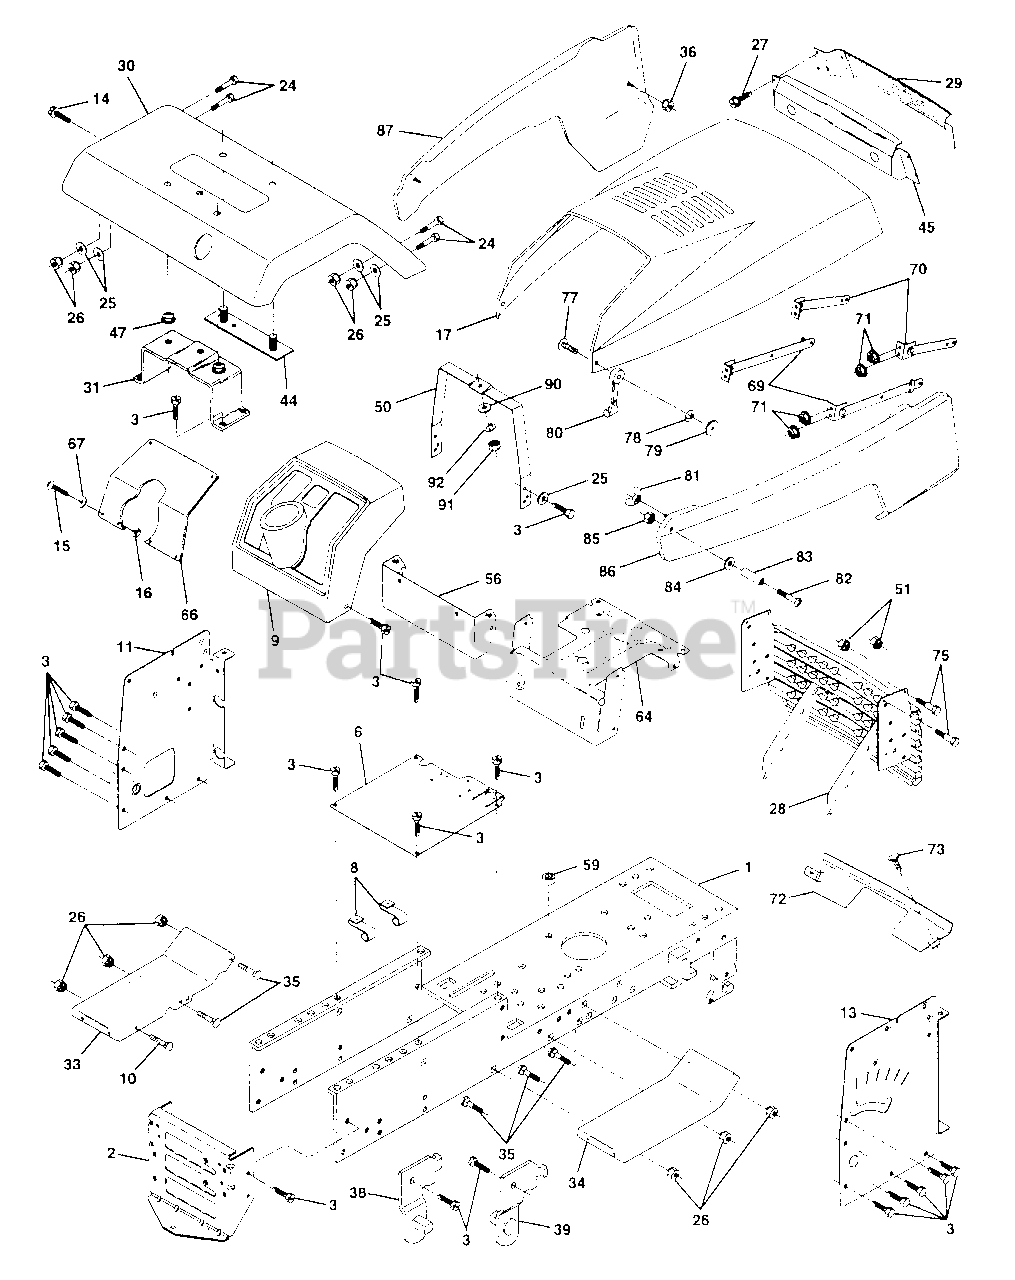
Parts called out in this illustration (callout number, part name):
1	Chassis Weldment 11 Ga
2	Drawbar Stretch
3	Screw Thdrol 3/8 - 16 x 3/4 Ty-TT
8	Clip Insulator
9	Dash Black Yard Pro
10	Bolt Carriage 3/8-16 Unc x 1
11	Panel Pnt Dash Lh
13	Panel Pnt Dash Rh
14	Screw Thdrol 3/8 - 16 x Ty-TT
15	Screw Mach Trhd 5/16 - 18 UNC x 3/4
16	Nut Keps 5/16 - 18 UNC
24	Bolt Fin Hex 3/8 - 16 Unc x 1
25	Washer 13/32 x 13/16 x 12 Ga
26	Nut Lock 3/8 - 16 Unc
27	Screw Lock Spider #8 x 7/8
29	Lens/Clip Asm Bar Clear
31	Bracket Pnt Fender
33	Footrest Pnt Lh
34	Footrest Pnt Th
35	Bolt Rdhd Sht Sqnk 3/8 - 16 x 3/4
36	Nut Pal
38	Bracket Asm Pivot Lh
44	Strap Asm. Fender
45	Bezel Asm. Pnt
47	Nut Push Nylon
50	Support Pnt Dash
51	Nut Lock, W/Insert 1/4 - 20 UNC
56	Dash Extension
59	Bushing Snap Split
64	Dash Pnt Lower
66	Plate Silkscreened Dash
67	Washer 11/32 x 11/16 x 16 Ga
69	Strap Asm Pnt Hinge Rear (blk)
70	Strap Asm Pnt Hinge Front
71	Nut Keps Hex 1/4 - 20 UNC
73	Screw Taptite 1/4-20 x 1/2
75	Bolt, Shoulder 1/4 - 20 UNC
77	Screw Mach Cr Pan #10-24 x 1/2
78	Washer Lock #10
79	Nut Weld .327/.304 #10 - 24
80	Latch Chute Blk
81	Nut Plastic Locking Wng 1/4 - 20
82	Screw Mach Cr Pan #10 - 24 x 1-1/4
83	Spacer Split #10 x 3/4 Cad/Zin
84	Washer 7/32 x 1/2 x 18 Ga
85	Nut Keps #10 - 24 Unc
86	Panel Pnt Rh Side
87	Panel Pnt Lh Side
90	Washer 9/32 x 3/4 x 16 Ga
91	Nut Fin Hex 1/4 - 20 Unc
92	Washer Lock Hvy. Helical 1/4
